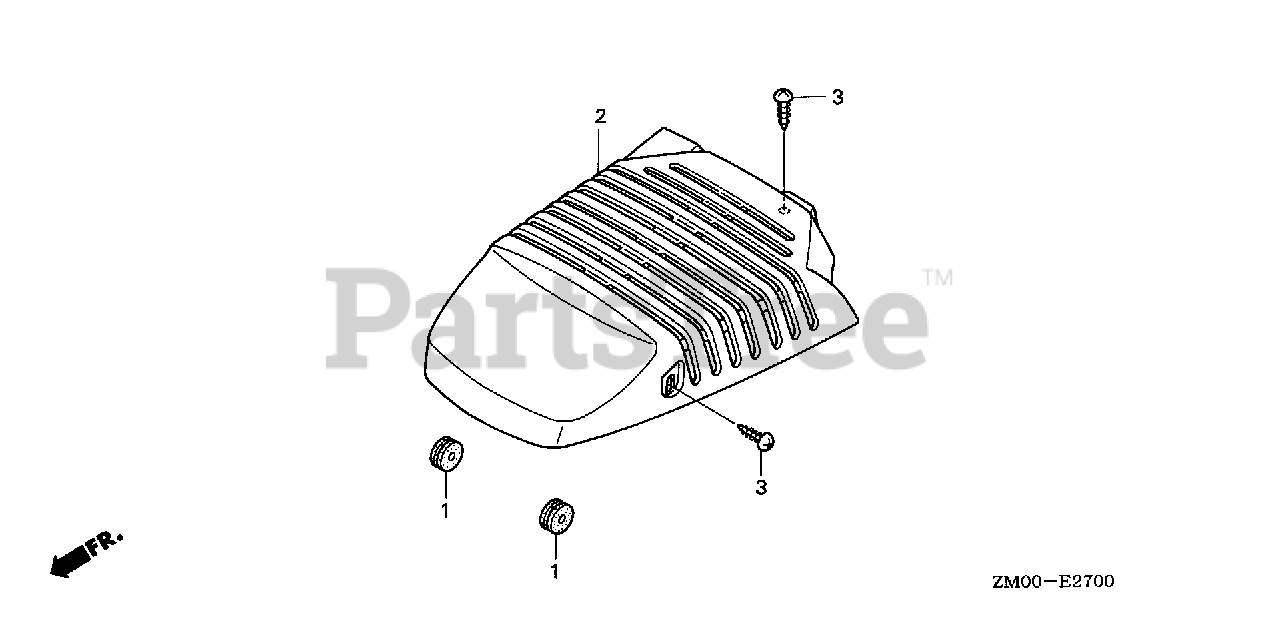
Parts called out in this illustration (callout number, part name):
1	GROMMET, CHOKE ROD
2	COVER, TOP *NH1* (BLACK)
3	SCREW, TAPPING (4X16)
